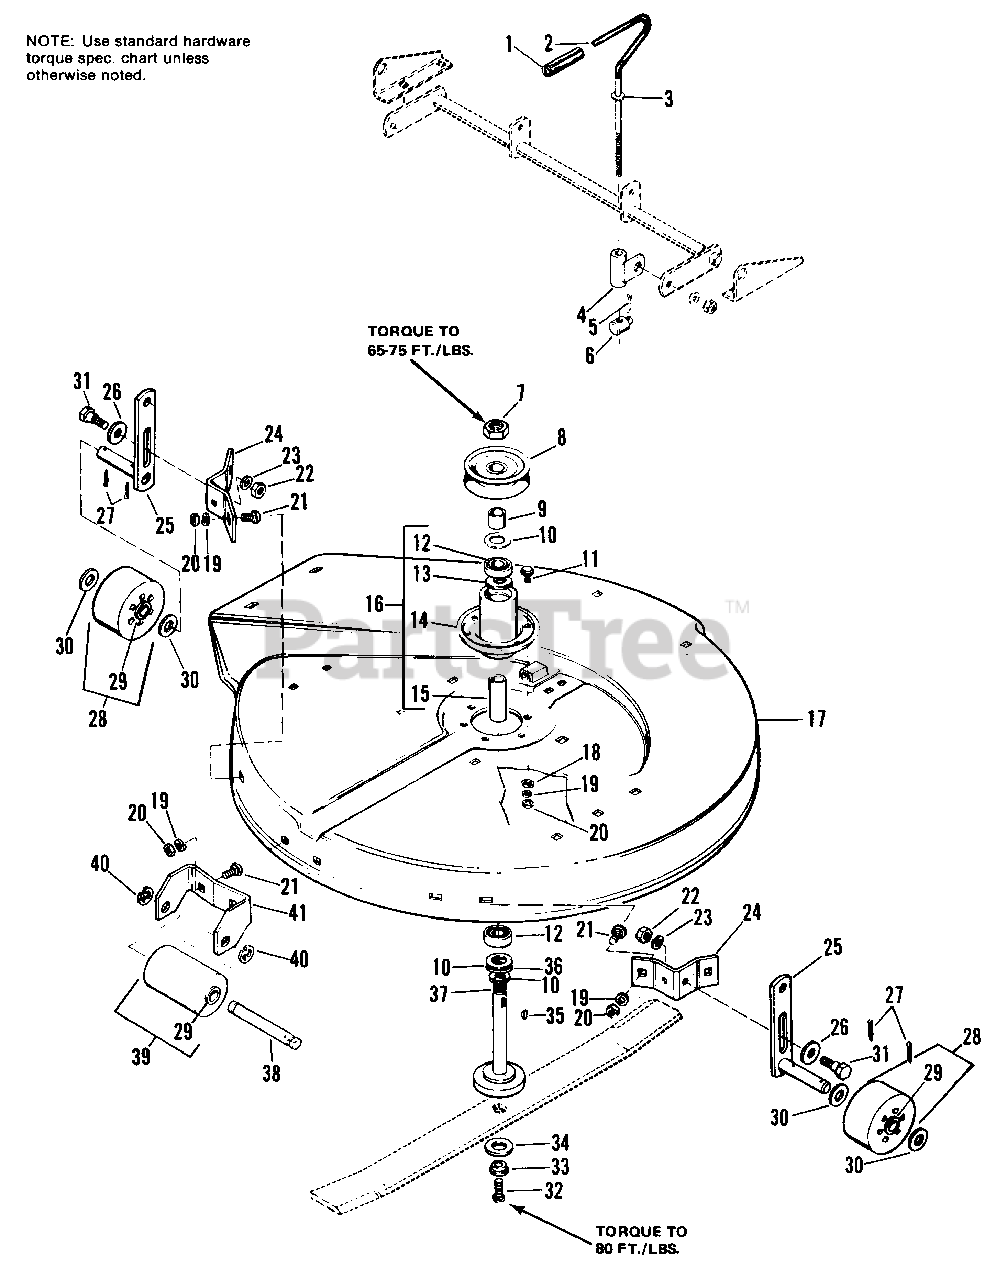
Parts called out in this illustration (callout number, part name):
2	HANDLE, Adjusting
3	WASHER, Plain, 3/8
4	GUIDE ASSY., Rod
5	PIN, Cotter, 3/32 x 1
7	LOCKNUT, Hex, 3/4-16
11	CAPSCREW, Hex Hd., 5/16-18 x 3/4
12	BEARING, Ball
13	RING, Backing
14	ARBOR & TUBE ASSY.
16	TUBE ASSY., W/Bearings
17	HOUSING, 26"
18	WASHER, Plain, 5/16
19	LOCKWASHER, 5/16
20	NUT, Hex, Full, 5/16-18
21	BOLT, Carriage, 5/16-18 x 5/8
22	NUT, Hex, Full, 3/8-16
23	LOCKWASHER, 3/8
24	BRACKET, Roller
25	SHAFT ASSY., Roller
26	WASHER, Plain, 7/16
27	PIN, Cotter, 3/16 x 1
28	ROLLER ASSY.
30	WASHER, Plain, 5/8
31	BOLT, Shoulder, 3/8-16 X 1.34
32	CAPSCREW, Hex Hd., 1/2-20 x 1/2
33	WASHER, Shoulder
34	WASHER, Belleville
35	KEY, Woodruff, #61
37	ARBOR ASSY.
38	SHAFT, Center Roller
39	ROLLER ASSY.
40	RING, Retaining
41	BRACKET, Center Roller
42	ARBOR & HOUSING ASSY.
